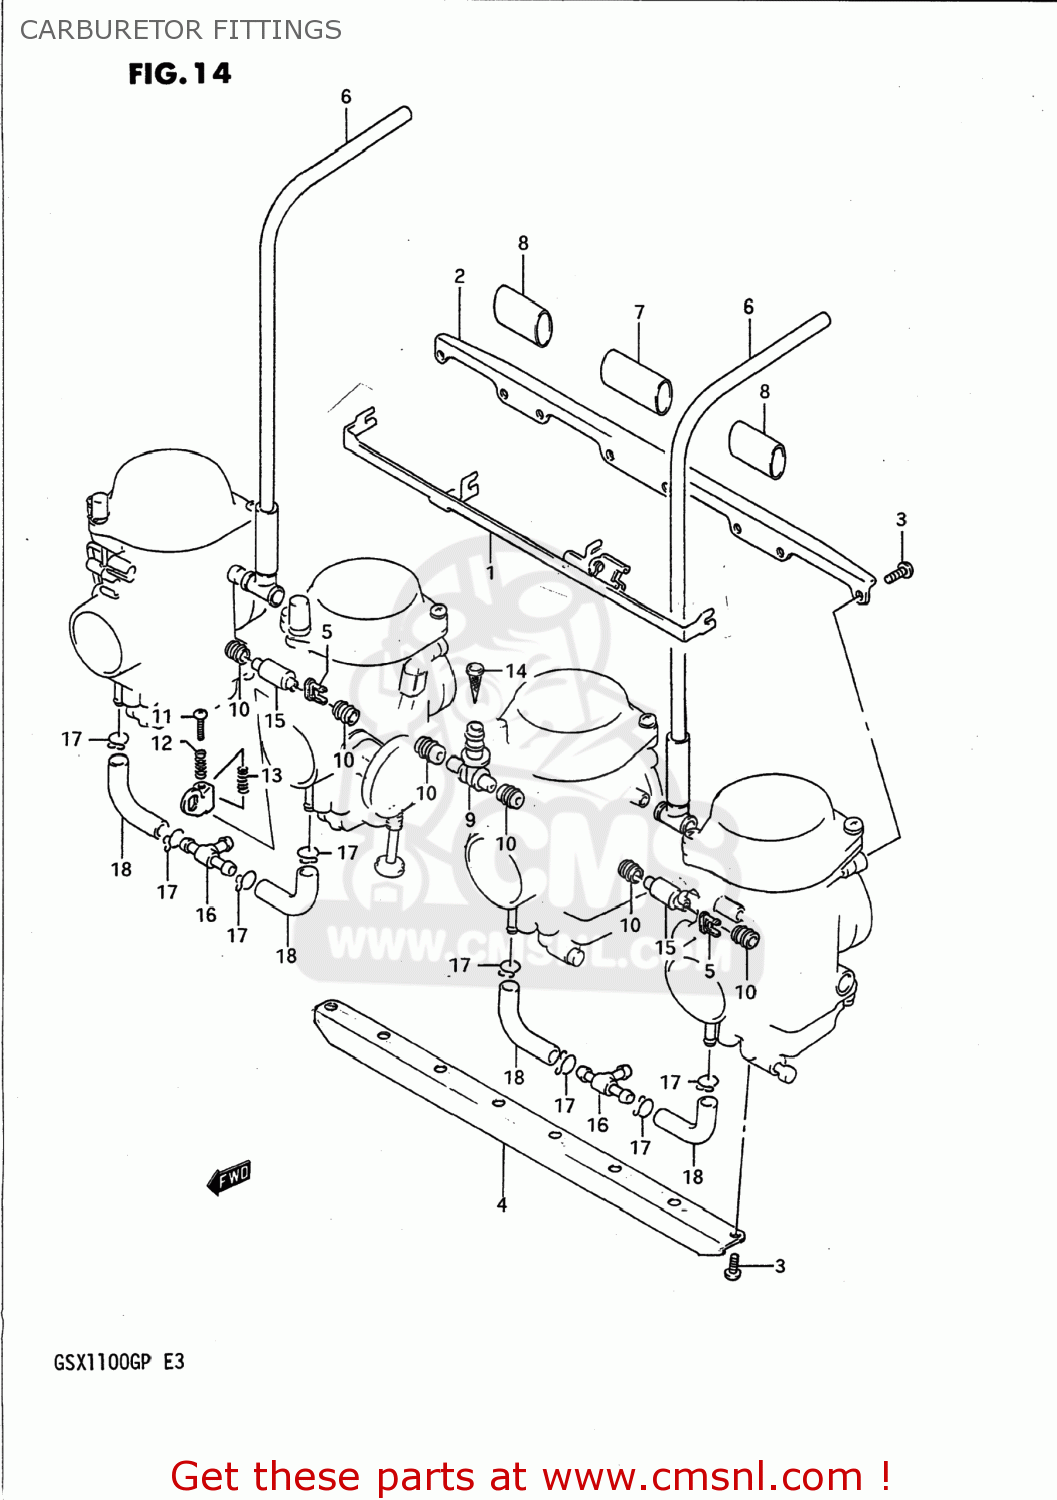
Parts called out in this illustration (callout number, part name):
1	LEVER
2	PLATE
3	SCREW
4	PLATE
5	HOLDER
6	HOSE
7	HOSE
8	HOSE
9	NIPPLE
10	SEAL
11	SCREW
12	SPRING
13	SPRING
14	FILTER
15	PIPE
16	NIPPLE
17	CLIP
18	HOSE
